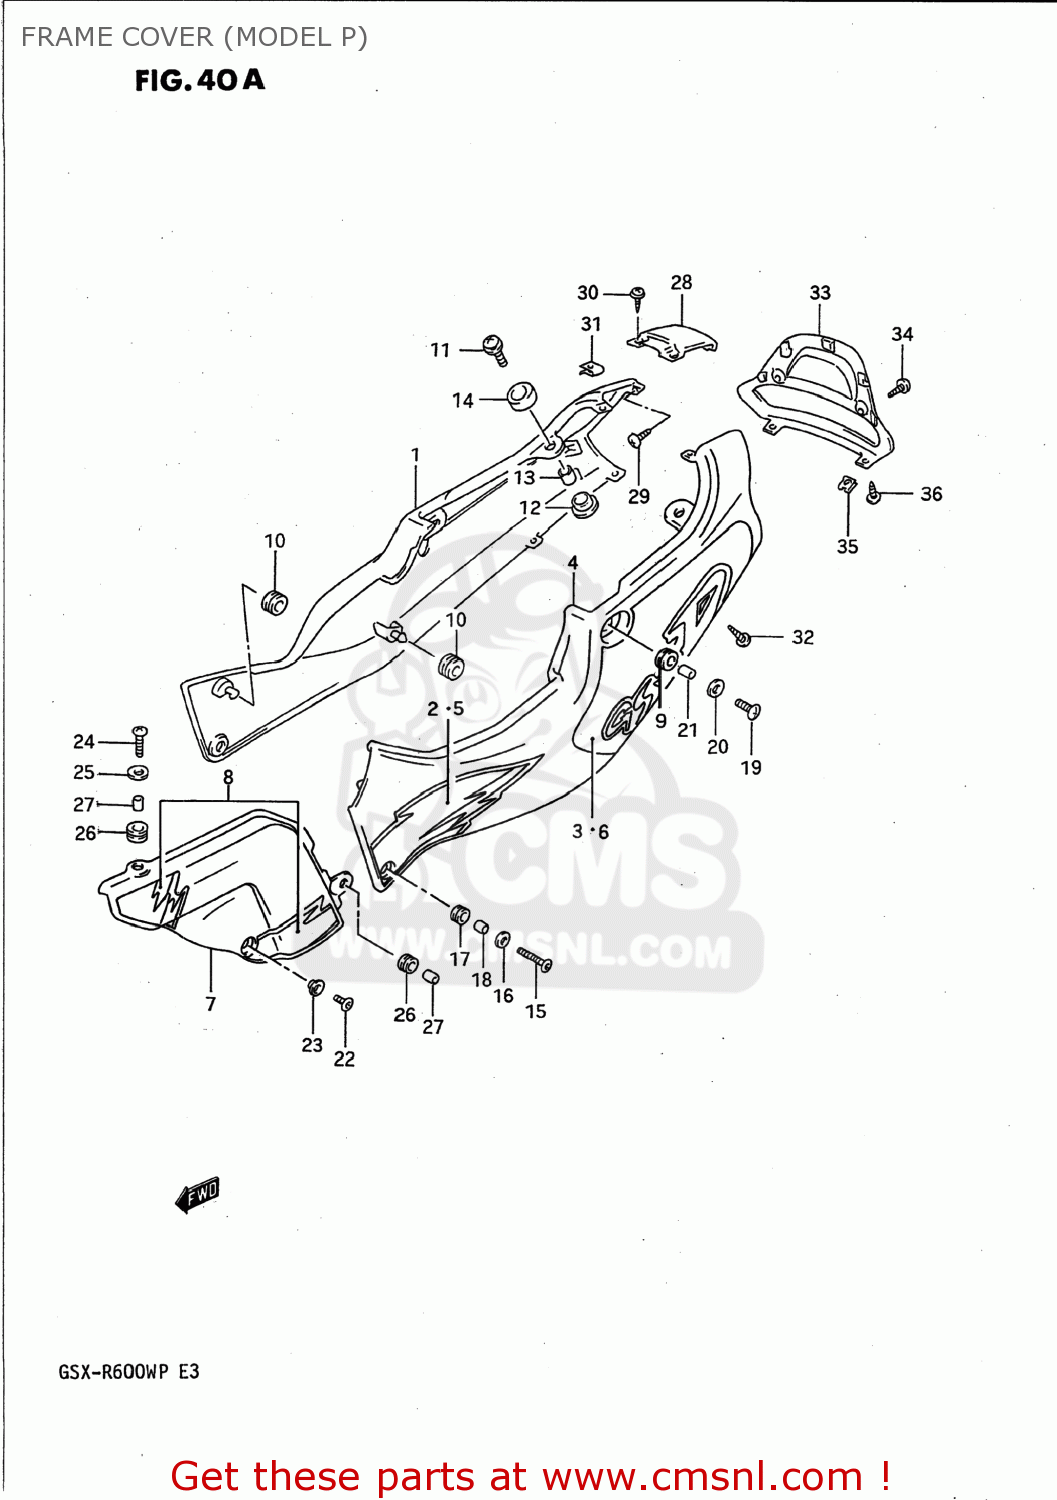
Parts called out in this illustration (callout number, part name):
1	COVER, FRAME RH (BLACK)
2	TAPE,FRAME COVER STRIPE
3	TAPE,FRAME COVER ZECKE
4	COVER ASSEMBLY,FRAME,LEFT
5	TAPE,FRAME COVER STRIPE
6	TAPE,FRAME COVER STICKER
7	COVER ASSEMBLY,FRAME BODY
8	TAPE SET,FRAME COVER B
9	CUSHION
10	CUSHION
11	SCREW(6X30)
12	CUSHION,FRAME COVER LWR
13	SPACER
14	CUSHION,TAIL COVER UPR
15	SCREW(6X30)
16	WASHER
17	CUSHION
18	SPACER (6.1X9X9)
19	SCREW(6X20)
20	WASHER(6,5X22X1.6)
21	SPACER (6.3X9.1X6.7)
22	SCREW(5X14)
23	WASHER
24	SCREW(6X25)
25	WASHER (6.5X18X1.6)
26	CUSHION
27	SPACER (6.1X9X9)
28	COVER ASSY,FRAME CTR
29	SCREW(5X12)
30	SCREW
31	NUT
32	SCREW
33	COVER,FRAME RR
34	SCREW(5X12)
35	NUT
36	SCREW
